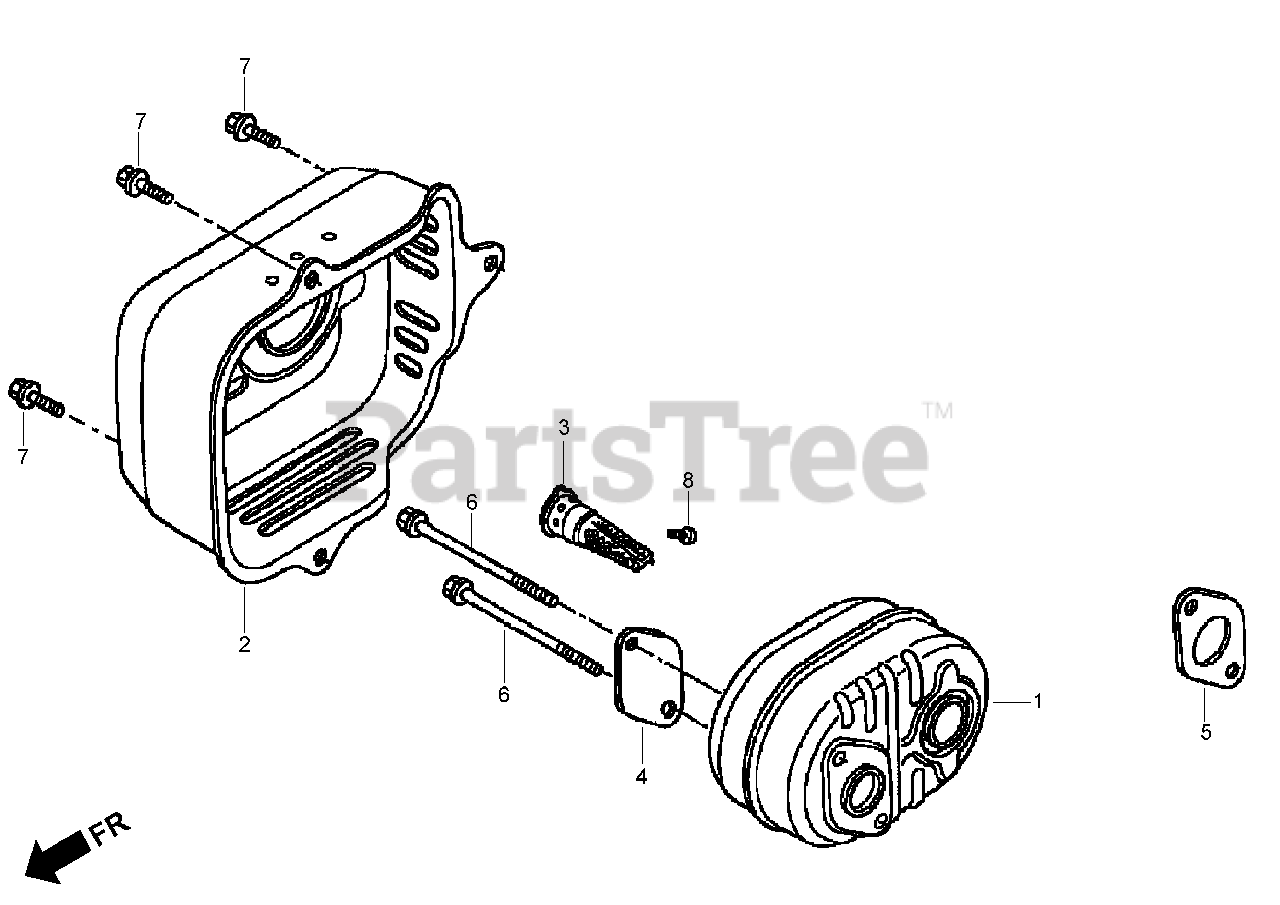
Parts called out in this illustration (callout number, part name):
1	MUFFLER
2	PROTECTOR-MUFFLER
3	ARRESTER-SPARK
4	PLATE-NUMBER, ARRESTER
5	GASKET-MUFFLER
6	BOLT-FLANGE (6X79) (C T200)
7	BOLT-FLANGE (6X12) (C T200)
8	SCREW-TAPPING (4X6)
